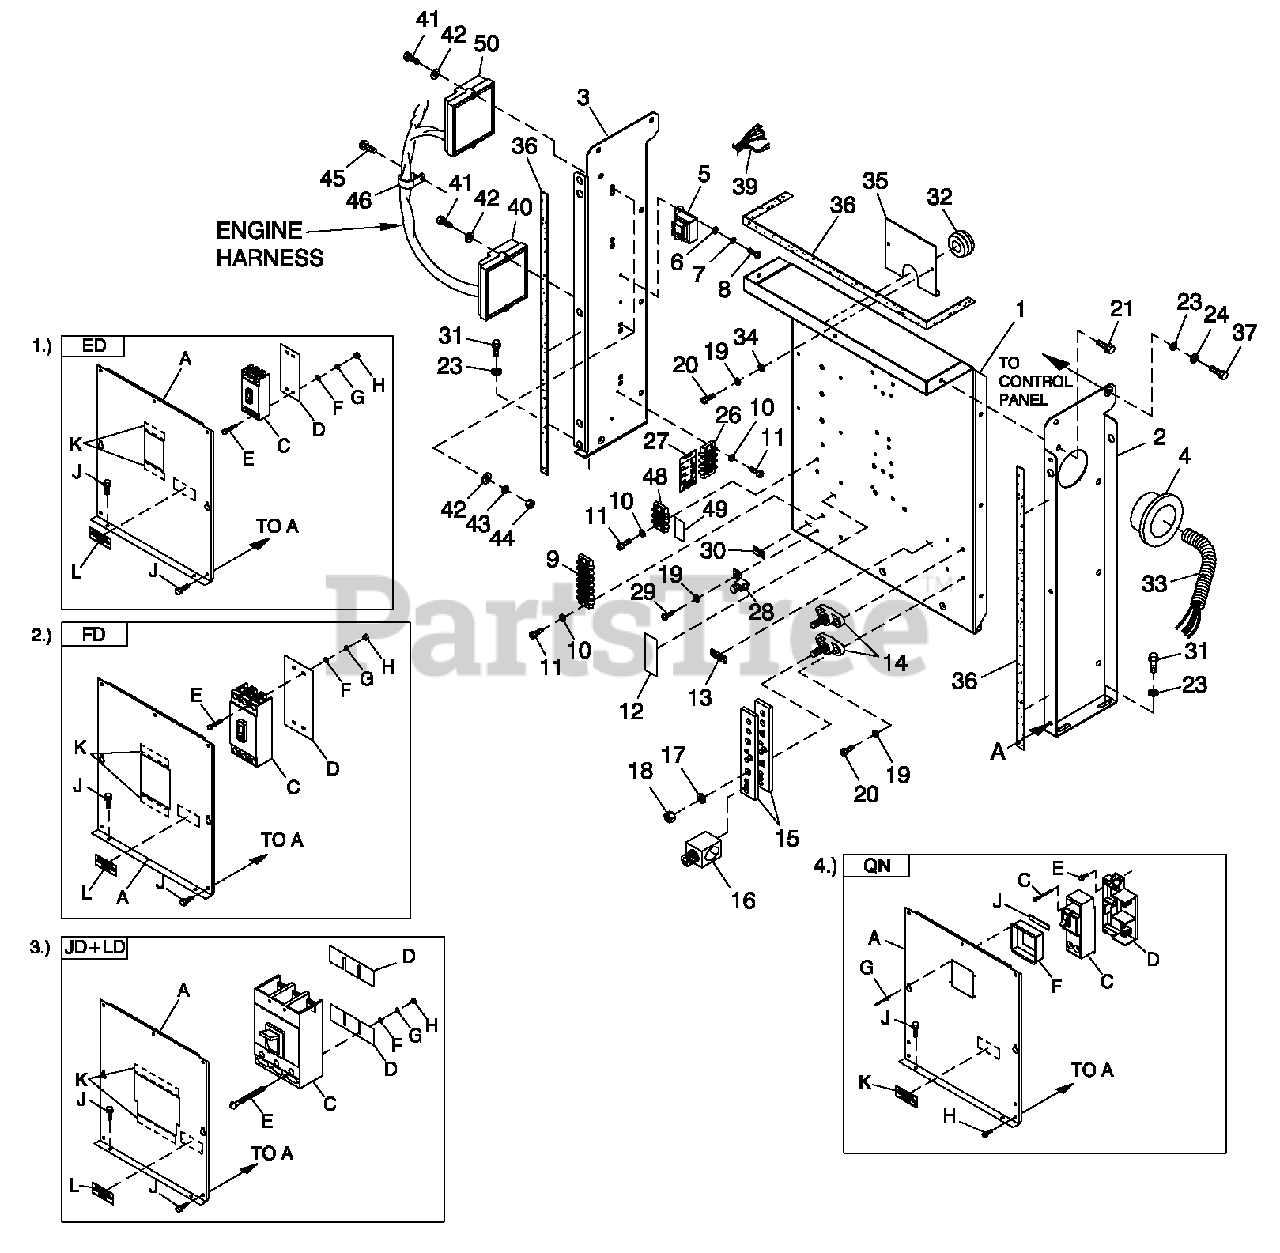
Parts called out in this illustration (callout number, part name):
1	PAN CB CONN BOX
1	UL CIRCUIT BREAKER (ED)
2	STAND RH CONTROL
2	UL CIRCUIT BREAKER (FD)
3	STAND LH CONTROL
3	UL CIRCUIT BREAKER (JD+LD)
4	BUSHING SNAP SB-2.5-31
4	UL CIRCUIT BREAKER (QN)
5	XFMR DUAL 120V/16V (FOR 120/240V & 277/480V UNITS)
6	WASHER FLAT M4
7	WASHER LOCK #8-M4
8	SCREW PHTTM4-0.7X 10 ZYC
9	BLOCK TERM 20A 6 X 6 X 1100V
10	WASHER LOCK #6
11	SCREW PHTT #6-32X1/2 ZYC
12	DECAL RTS CUSTOMER CONNECTION
13	DECAL NEUTRAL
14	JUNCTION BLOCK 3/8-16
15	BUS BAR NEUTRAL BLOCK 390
16	LUG SLDLSS 600/250-1/0 X 1/4-28
17	WASHER LOCK 3/8
18	NUT HEX 3/8-16 STEEL
19	WASHER LOCK M5
20	SCREW PHTT M5-0.8X 16 ZYC
21	SCREW THF M6-1 X 16 N WA Z/JS
23	WASHER FLAT 1/4-M6 ZINC
24	WASHER LOCK M6-1/4
26	BLOCK TERM 20A 6 X 3 X 1100V
27	DECAL CHARGER POWER 120VAC C2
28	LUG SLDLSS #6-14X 13/64 CU
29	SCREW HHTT #10-32X3/8 CZ
30	DECAL GROUND LUG
31	SCREW HHTT M6-1.0X 16 ZYC
32	GROMMET 1.25 X .25 X .75
33	CONDUIT FLEX 2.0" ID (36" LG)
34	WASHER FLAT M5
35	PLATE WIRE SNGLGALV
36	TAPE ELEC 1/2 FOAM (AS REQ'D)
37	SCREW HHC M6-1.0X 16G8.8
39	HARNESS, TRANSFORMERADAPTER
40	PCB ENCLOSURE ASSY 4.2L IGN MD
41	SCREW PPHM #10/32X2
42	WASHER FLAT #10 ZINC
43	WASHER LOCK #10
44	NUT HEX #10-32 STEEL
45	SCREW THF M6-1 X 16 N WA Z/JS
46	CLAMP VINYL 1.06 X .406 Z
47	SEAL WEATHER .45"DIA
48	BLOCK TERM 20A 2 X 6 X 1100V
49	DECAL GTS CUSTOMER CONNECTION
50	ASSY PCB IGN MOD 2.4L NO-TURBO
A	COVER ED CB SHORT STND
C	CB0050A3P 480V SED4 LL
D	INSULATOR CBS(ED-3P)
E	SCREW RHM #10-32X4-1/2
F	WASHER FLAT #10 ZINC
G	WASHER LOCK #10
H	NUT HEX #10-32 STEEL
J	SCREW THF M6-1 X 16 N WA Z/JS
K	TAPE ELEC 1/2 FOAM (AS REQ'D)
L	DECAL CUSTOMER CONNECT INSIDE
A	COVER CB CONN BOX
C	CB0150A3P 600V SFD6 LL
D	INSULATOR CB FD FRAME 30MIL
E	SCREW SHC 1/4-20 X 4.5 G8.8 NZ
F	WASHER FLAT 1/4-M6 ZINC
G	WASHER LOCK M6-1/4
H	NUT HEX 1/4-20 STEEL
A	COVER JD/LD CB SHRT STAND
C	CB0300A3P 600VS JD6LL
D	INSULATOR CIRCUIT BR. JD/LD
E	SCREW RHM 1/4-20X3
A	COVER QNFRMCB
C	CB 0150A 2P 240V S QN2 LL
D	BASE, QN CIRCUIT BREAKER
E	SCREW HHTT M5-0.8X 10 BP
F	COVER QNCB DISH
G	RIVET POP .125X .275SS
H	SCREW THF M6-1X16 N WAZ/JS
J	TAPE ELEC 1/2 FOAM (AS REQ'D)
K	DECAL CUSTOMER CONNECT INSIDE
